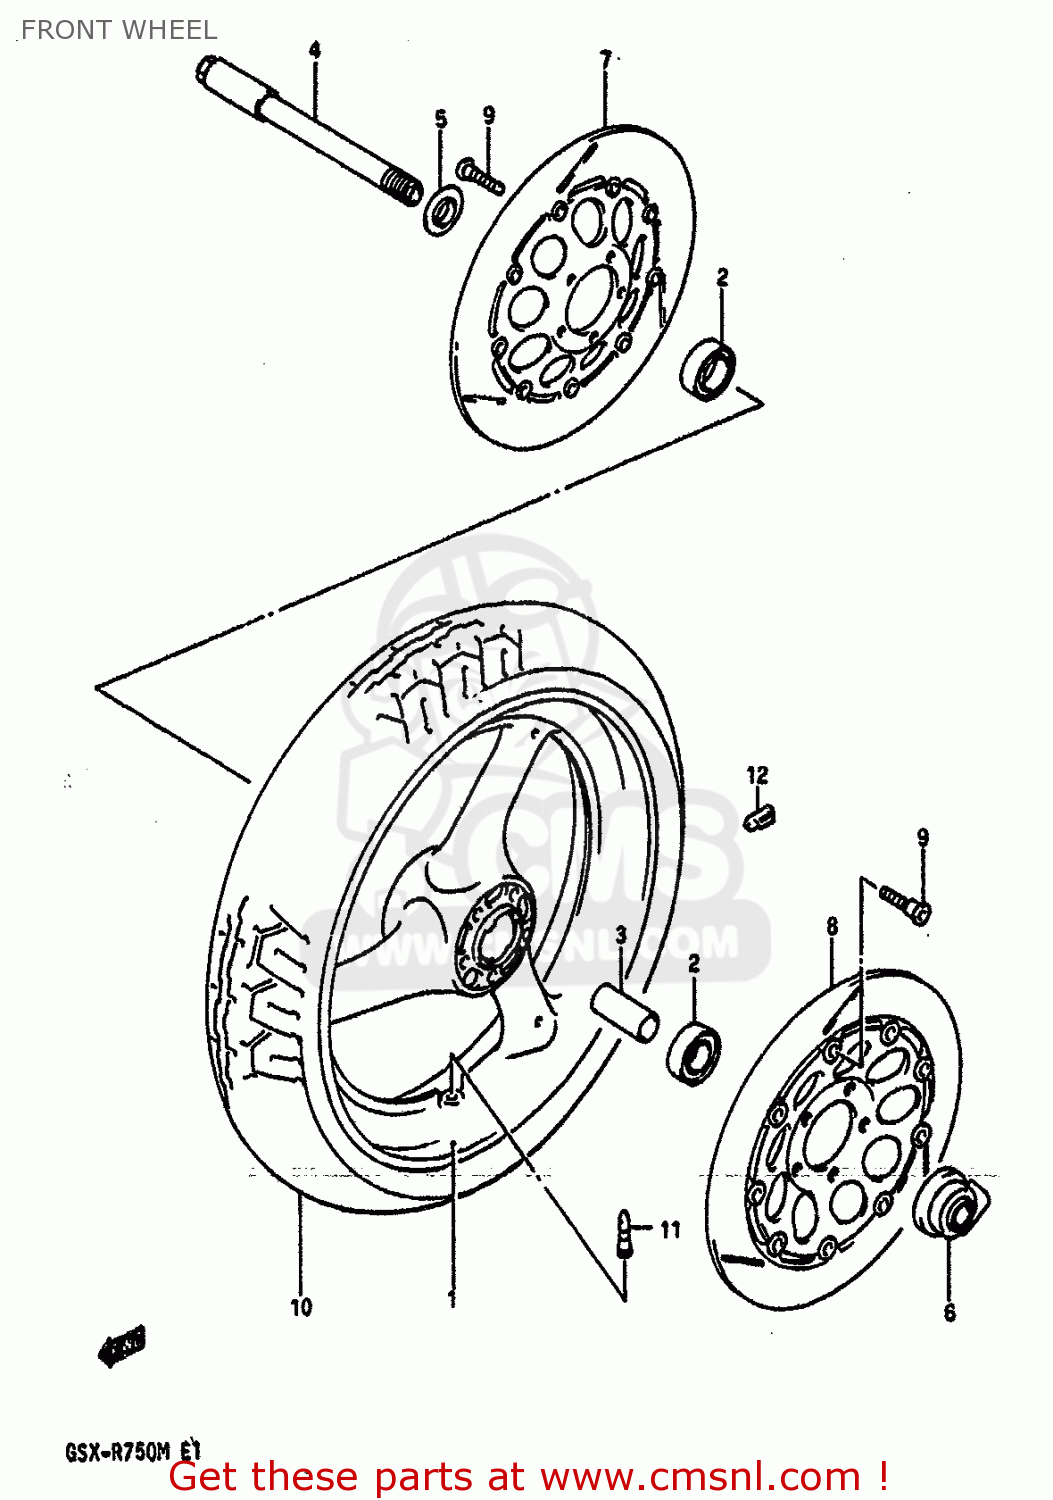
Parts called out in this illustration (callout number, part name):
1	WHEEL,FRONT
2	BEARING
3	SPACER(20.8X27.2X74)
4	AXLE,FR
5	SPACER,FR HUB BEARING,R
6	BOX ASSEMBLY,SPEEDOMETER GEAR
7	DISC,BRAKE
8	DISC,BRAKE
9	BOLT
10	TIRE,FRONT
11	VALVE ASSY,WHEEL RIM(TR412)
12	BALANCER,WHEEL
